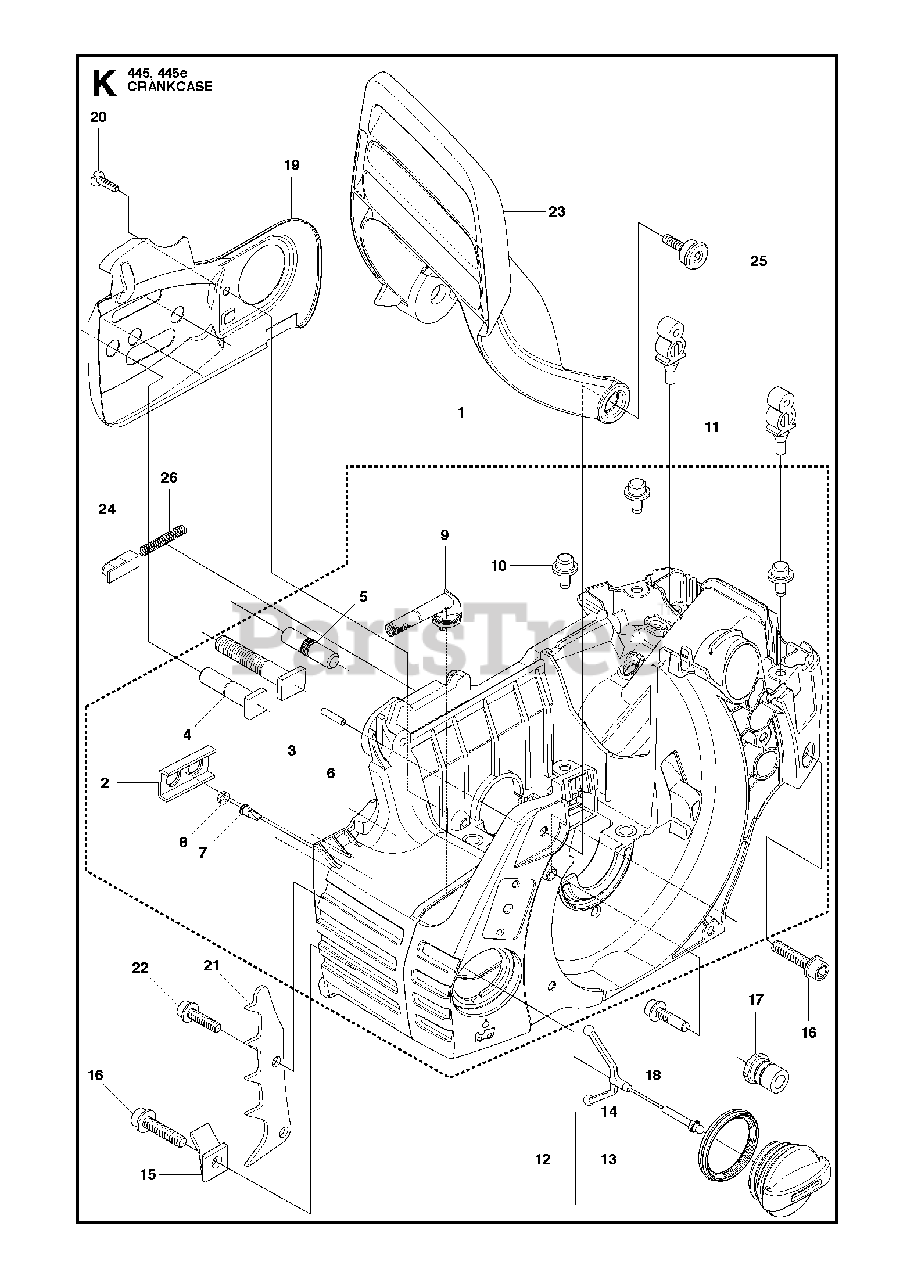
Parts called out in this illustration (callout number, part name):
2	STIFFENING PLATE
3	BAR BOLT
4	BAR BOLT (X2)
5	BAR BOLT
6	PIN
7	VALVE-CHECK (DUCKBILL)
8	PLUG
9	OIL SCREEN
10	GUIDE PEN
12	TANK CAP ASSY
13	SEALING
14	TANK LOCK
15	CHAIN CATCHER
17	LATERAL SUPPORT
18	SCREW IHSCFT
19	CHAIN GUIDE PLATE
21	FELLING DOG
23	HAND GUARD
26	LOCK SPRING
